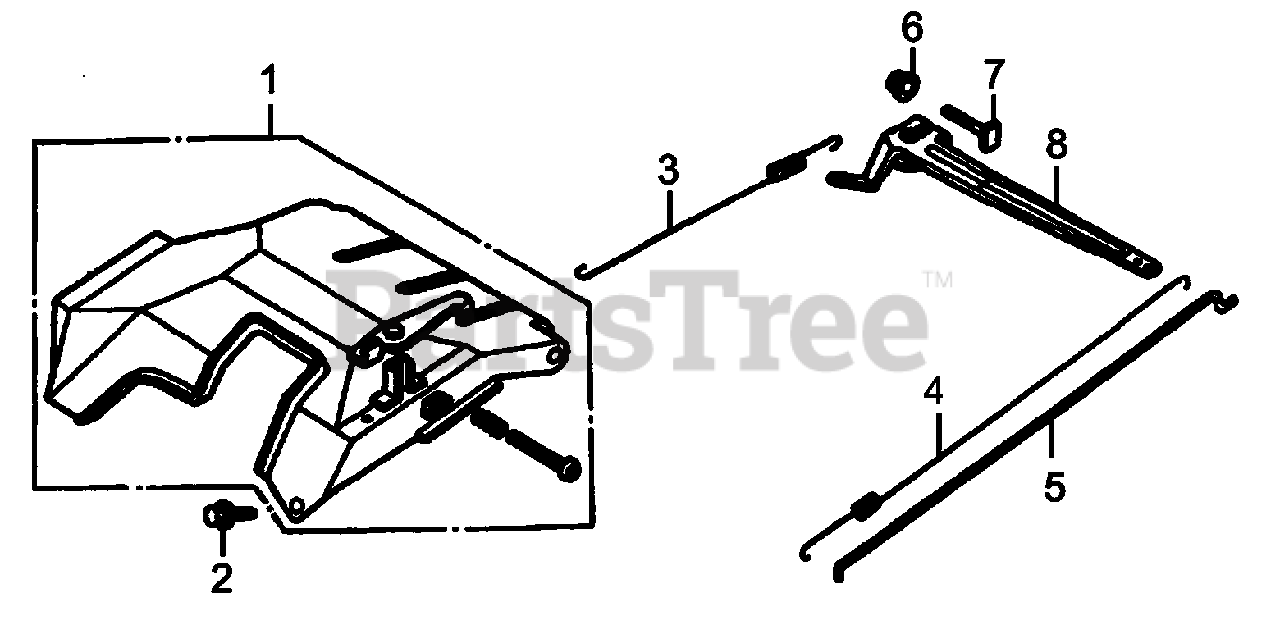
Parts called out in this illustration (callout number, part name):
1	CONTROL ASSY.
2	BOLT, FLANGE, 6X12
3	SPRING, GOVERNOR A
4	SPRING, GOVERNOR B
5	ROD, GOVERNOR
6	NUT, FLANGE, M6
7	BOLT, GOVERNOR ARM
8	ARM, GOVERNOR
